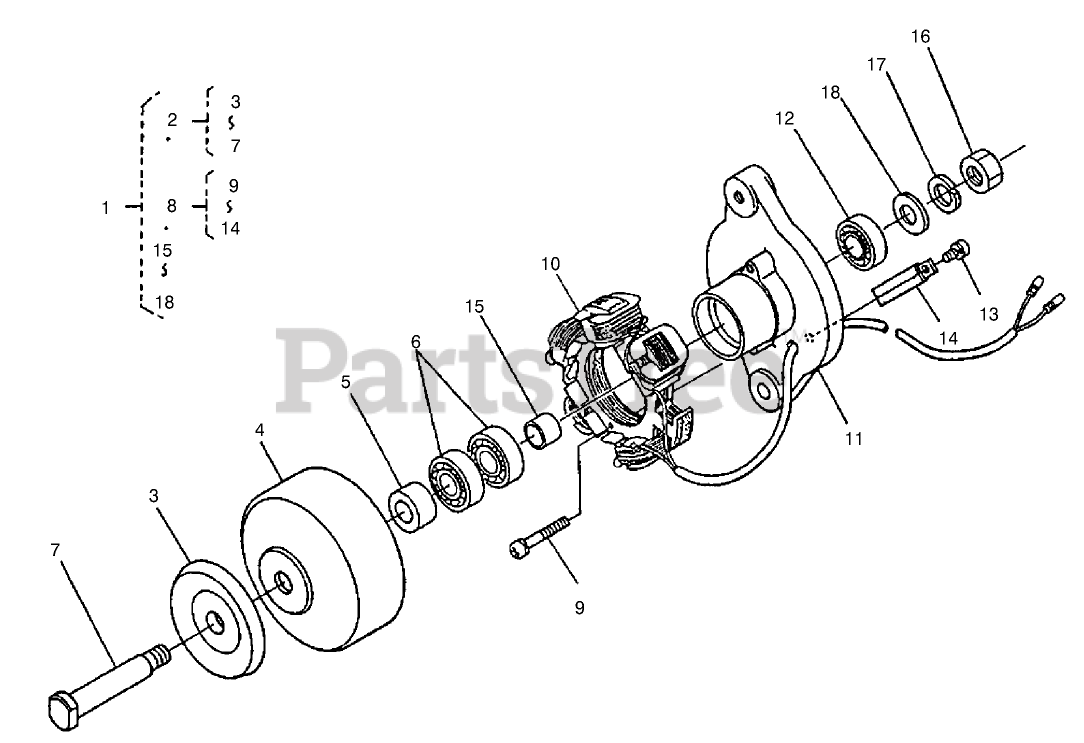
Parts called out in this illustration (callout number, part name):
1	ASSY DYNAMO
2	ROTOR ASM
3	PULLEY
5	COLLAR
6	BEARING-BALL
7	SHAFT-FAN
8	STATOR ASM
9	SCREW-HEAD, ROUND
10	STATOR
12	BEARING-BALL
13	SCREW-HEAD, ROUND
14	CLAMP-CORD
15	COLLAR
17	WASHER-SPRING
18	WASHER-PLAIN
